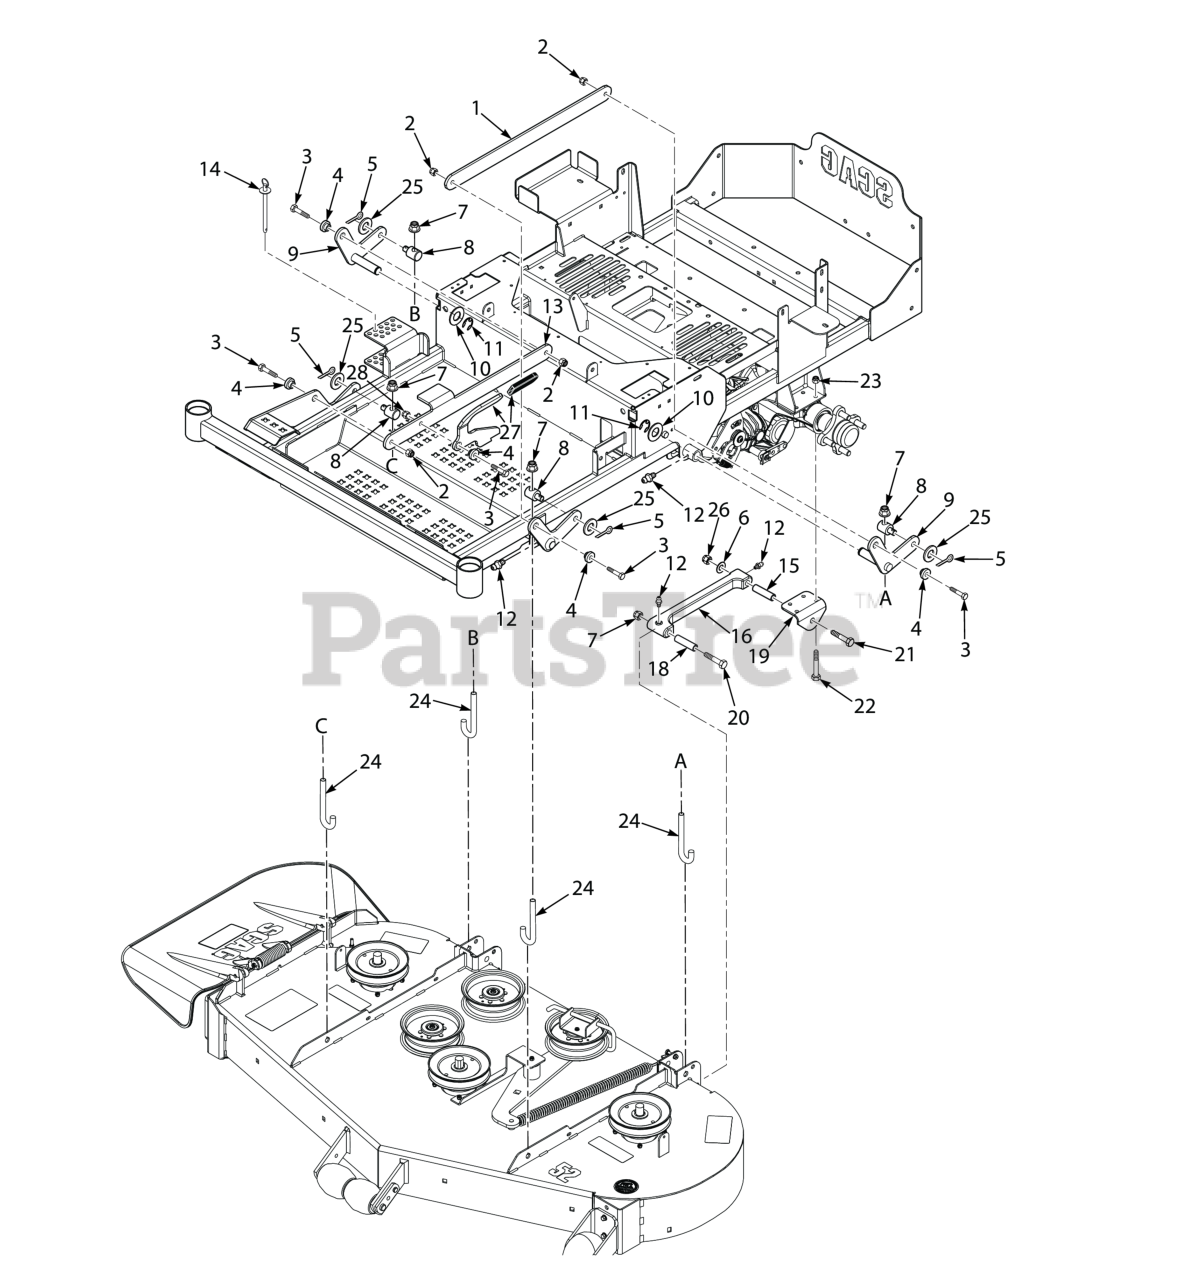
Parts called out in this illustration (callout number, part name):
1	Link, Deck Lift - LH
2	Nut, Flange Elastic Stop Nut, 3/8-16
3	Bolt, Hex Head 3/8-16 x 1-1/4", Kawasaki FX / FS
4	BUSHING, SPEED ADJUSTMENT LEVER
5	Pin, Cotter 3/16 x 1.0"
6	Flatwasher, 1/2 - .531 x 1.062 x .095
7	HEX LOCKNUT, ELASTIC STOP, 1/2-13
8	Joint, Swivel
9	Lift Bellcrank Weldment
10	Flatwasher, 3/4 (.766 x 1.250 x .060)
11	RETAINING RING, 3/4" EXTERNAL "E"
12	GREASE FITTING, STR. 1/4-28 SELF TAP.
13	Link, Deck Lift - RH
14	Pin Assembly, Deck Height
15	Spacer, Pusharm - Axle
16	Pusharm Assembly, LH
17	Pusharm Assembly, RH
18	Spacer, Pusharm - Deck
19	Bracket, Push Arm Link
20	Bolt, Hex Head 1/2-13 x 3-1/2"
21	Bolt, Hex Hd. 1/2-13 x 2-1/2" (lower)
22	Bolt, Hex Head 5/16-18 x 3.00"
23	HEX NUT, ELASTIC STOP LOCK, 5/16-18
24	Rod, Deck Lift
25	Flatwasher, 5/8" (.656 x 1.312 x .095")
26	Locknut, Hex 1/2-13 Center Lock
27	Lever Assembly (incl. Grip)
28	HEX NUT, ELASTIC STOP LOCK, 3/8-16
